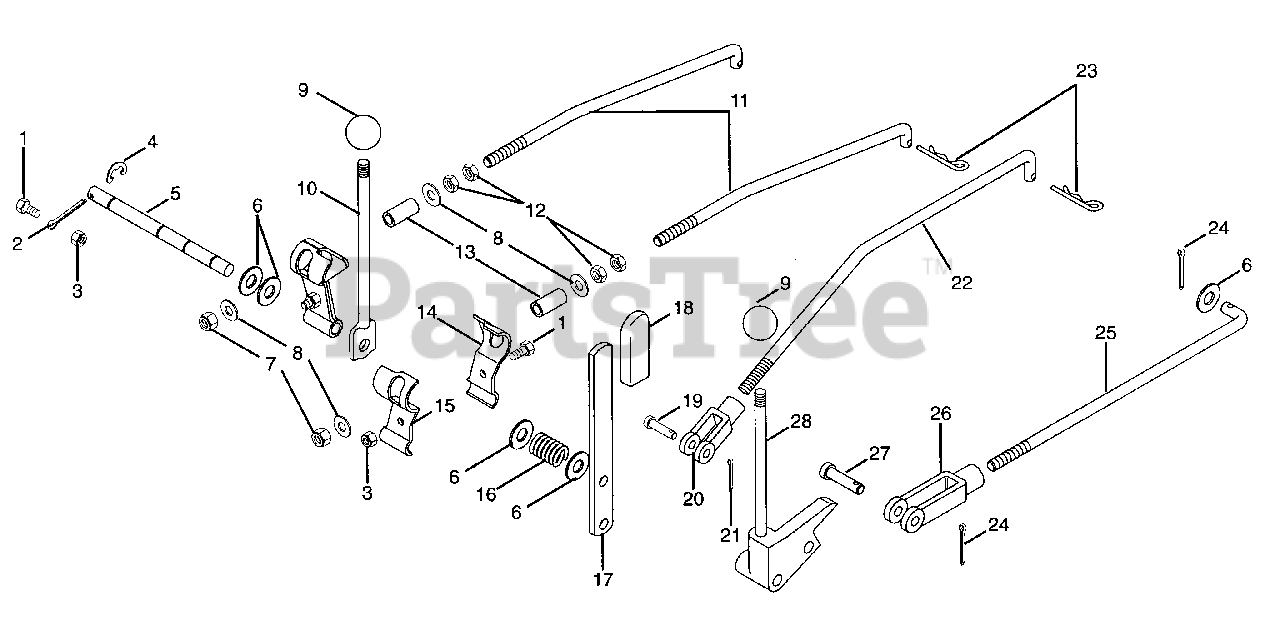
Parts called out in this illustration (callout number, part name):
1	Bolt-Hex .31-18 x .75 Grade 5
2	Pin-Cotter .250 x 2.00
3	Nut-Locking-Center .312-18 Grade 2
4	Ring-Retaining-External .500 x .042
5	Cross Shaft
6	Washer-Flat-Steel .531 x 1.062 x .095
7	Nut-Locking-Center .375-16 Grade 2
8	Washer-Flat-Steel .438 x 1.0 x .083
9	Knob-Control .438-20 x .50
10	Lever-Shift
11	Rod-Shift
12	Nut-Jam .375-16
13	Bushing-Sleeve .396 x .490 x 1.63
14	Arm-Shifter Right
15	Arm-Shifter Left
16	Spring-Compression .085 x .50 x 2.75
17	Lever-High-Low Shift
18	Grip-Handle
19	Pin-Clevis .375 x .948
20	Clevis .38-24 Adjustable
21	Pin-Cotter .09 x .75
22	Rod 2-Speed
23	Pin-Hair Internal .08 x .18 x 1.18
24	Pin-Cotter .12 x 1.0
25	Rod-PTO
26	Yoke .50-20, Adjustable
27	Pin-Clevis .500 x 1.213
28	Assembly-PTO Control
